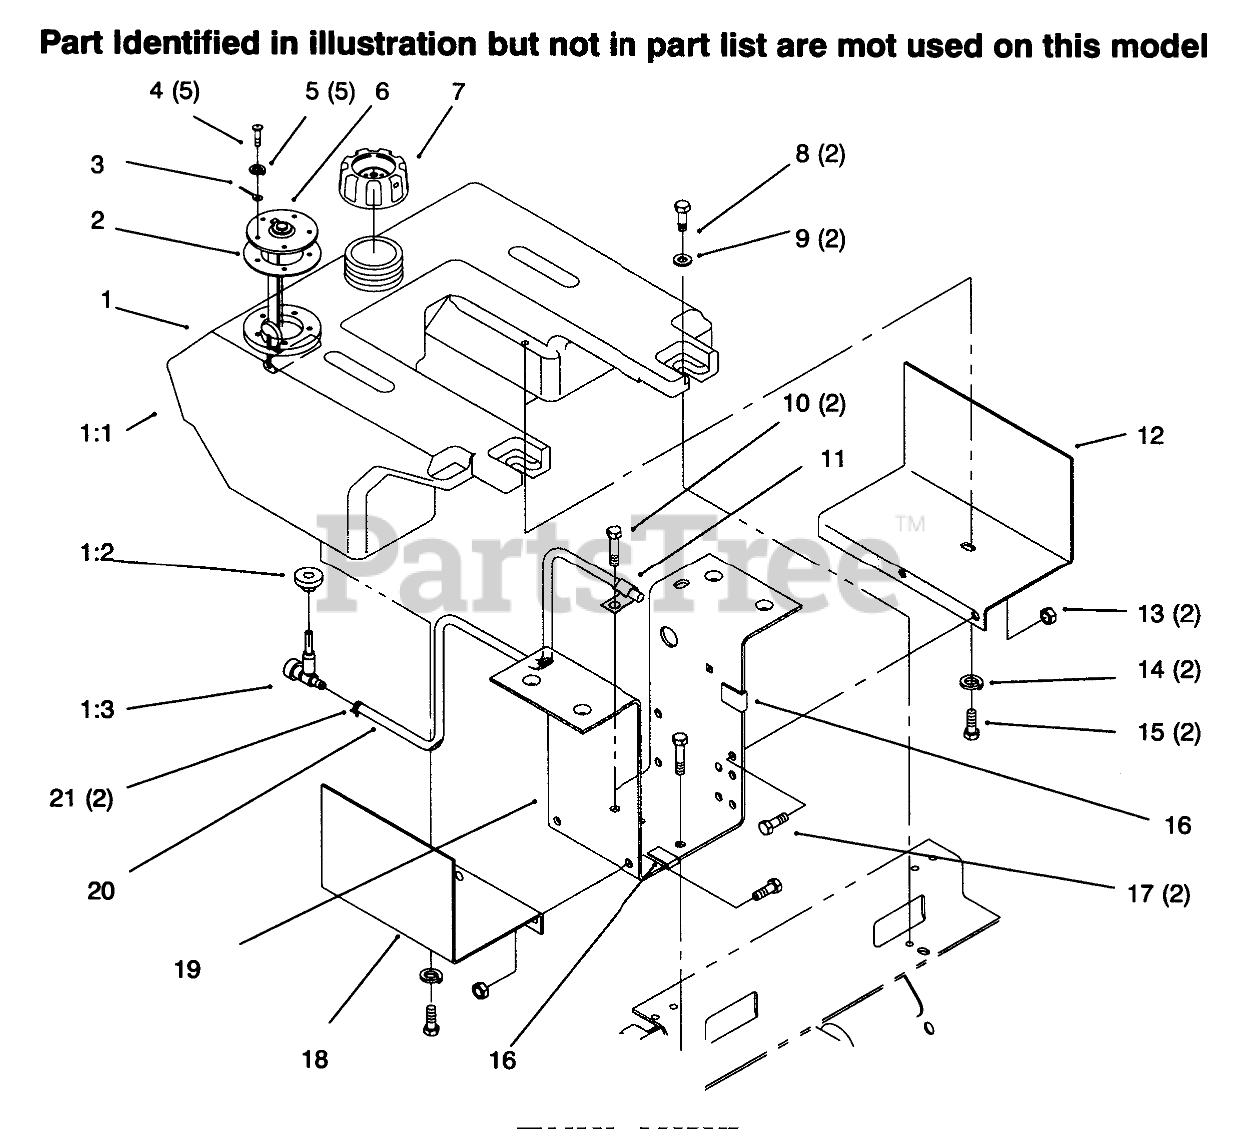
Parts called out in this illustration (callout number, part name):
1	TANK-FUEL
7	GAS CAP ASM
8	SCREW-HWHTF
9	WASHER-FLAT
10	SCREW-HH, LOCK
11	CLIP
12	Fuel Tank Support LH
13	NUT-LOCK, NI
14	WASHER-LOCK
15	SCREW-HH
16	SPEED CLIP
17	SCREW-HH
18	Support-FueITank RH
19	Bracket-Fender
20	Line-Fuel 62"
21	CLAMP-HOSE
